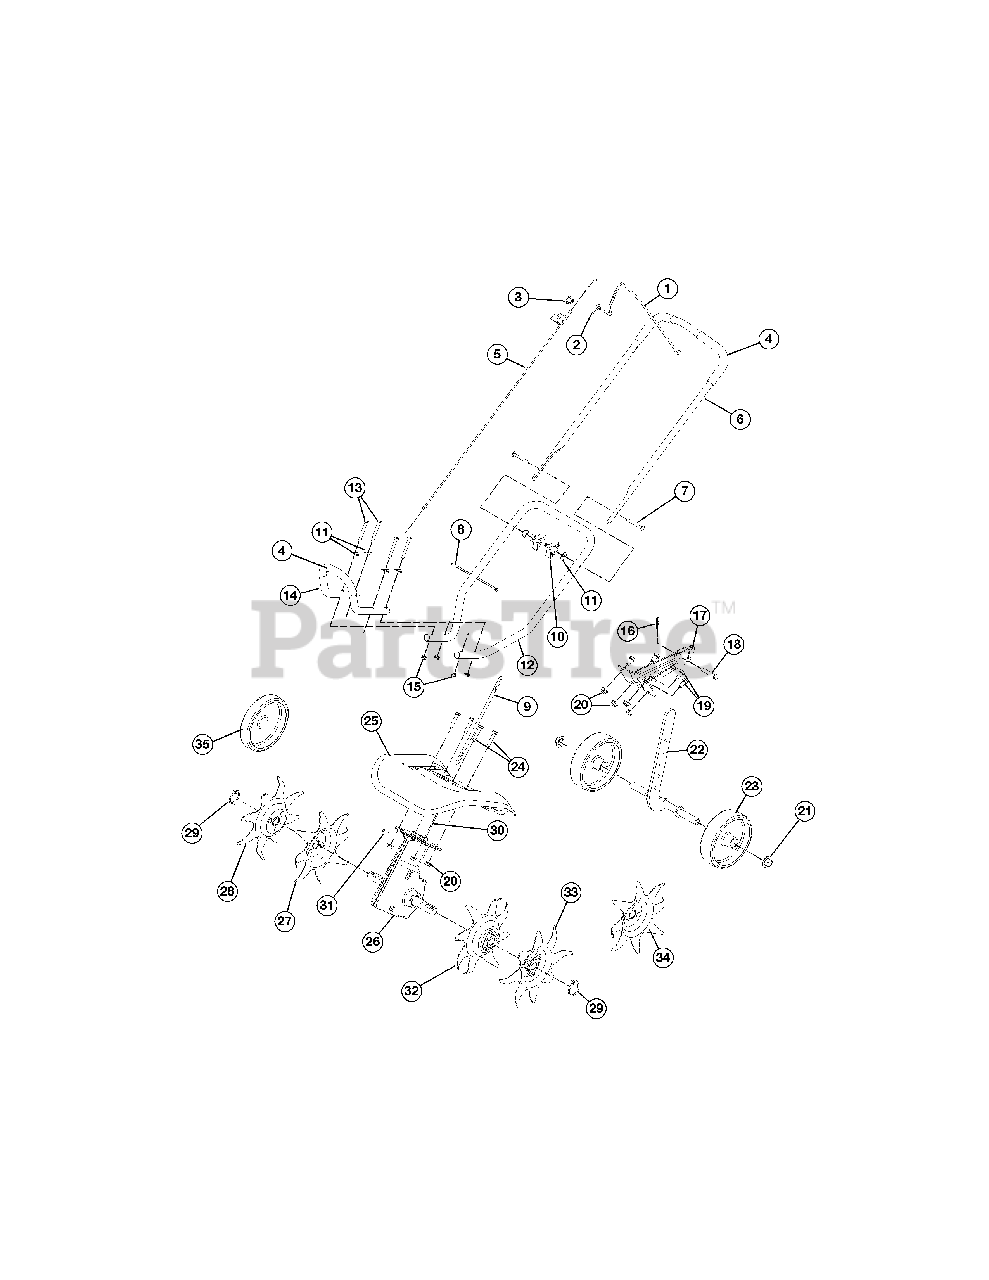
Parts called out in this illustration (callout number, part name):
1	Throttle Control
2	Torsion Spring
3	On/Off Switch
4	Foam Grip
5	Throttle Cable
6	Upper Handle
8	Cable Tie
9	Flex Shaft
11	Shoulder Washer
12	Lower Handle
13	Screw
14	Front Handle
15	Lock Nut
16	Cotter Pin
17	Tailpiece Bracket Assembly
18	Clevis Pin
19	Cap Screw
20	Lock Nut
21	Cap Push
22	Wheel Support Bracket Assembly
23	Wheel
24	Cap Screw
25	Tine Shield
26	Gear Box Assembly
27	Tine (Inner)
28	Tine (Outer)
29	Click Pin
30	Drive Shaft Housing
31	Sleeve Retaining Bolt
32	Tine (Inner)
33	Tine (Outer)
34	Edger Tine
35	Edger Wheel
